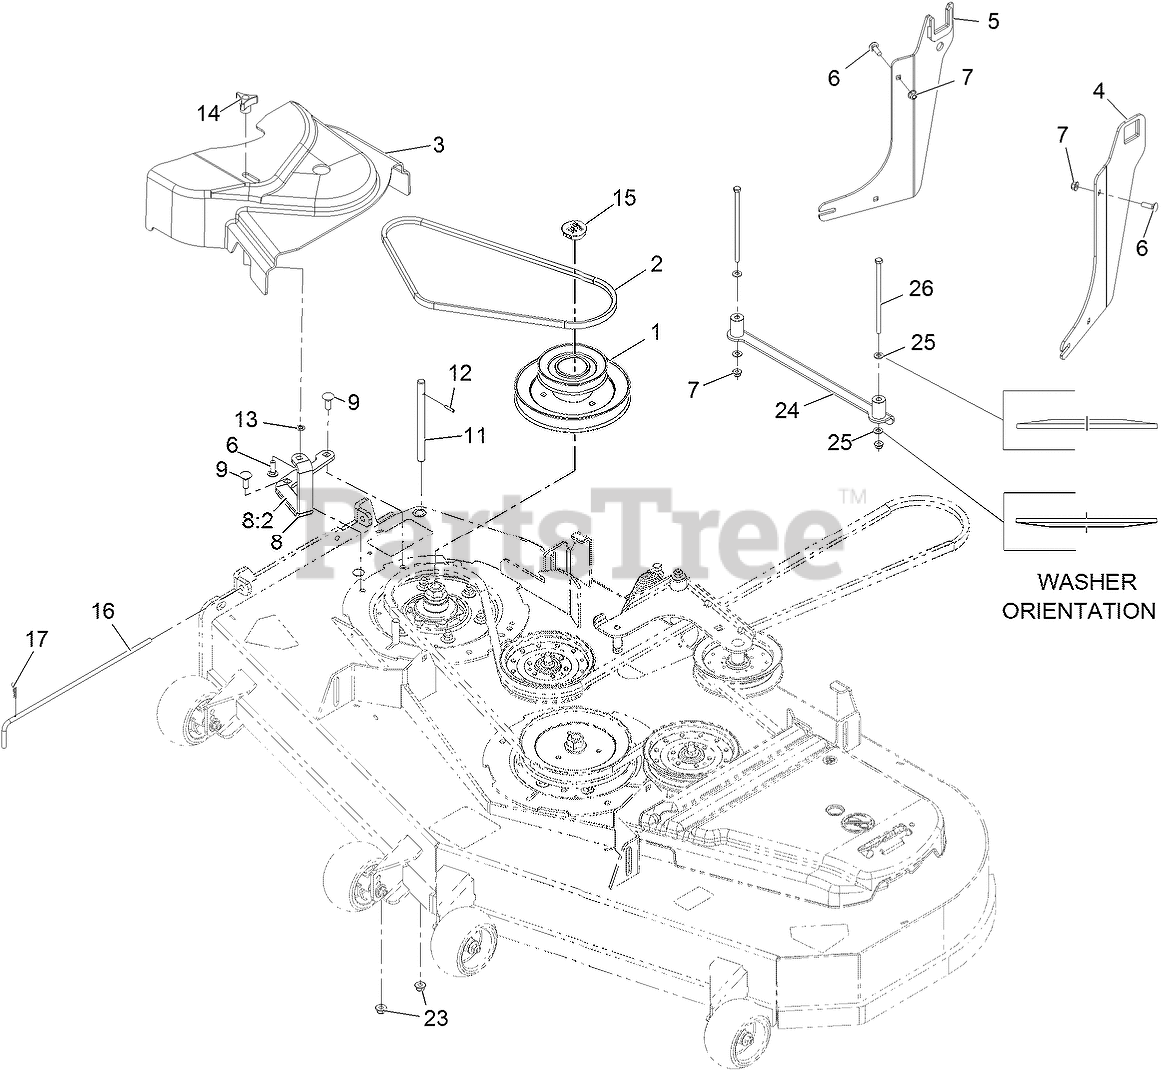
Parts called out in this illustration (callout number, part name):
1	JACKSHAFT,UV DRIVE 604 SPLINED
2	BELT,A 42.32
3	COVER-BELT UVE 60
4	BRACKET ASM, LH
5	BRACKET ASM, RH
6	BOLT-CARR
7	NUT-HF, NI
8	ASM-CVR BRKT W/DECAL
8:2	DECAL-COVER, MISSING
9	BOLT-CARR
11	SHAFT-CATCHER, GRASS
12	PIN-ROLL
13	RING-RETAINING, BOLT
14	KNOB-3 PRONG
15	PLUG, BLACK NYLON 1.75
16	PIN,CHUTE PIVOT
17	PIN-COTTER
23	Nut-Nyloc 3/8-16 Flg
24	ASM-HYDRO GUSSET
25	WASHER-SPRING
26	SCREW HH
